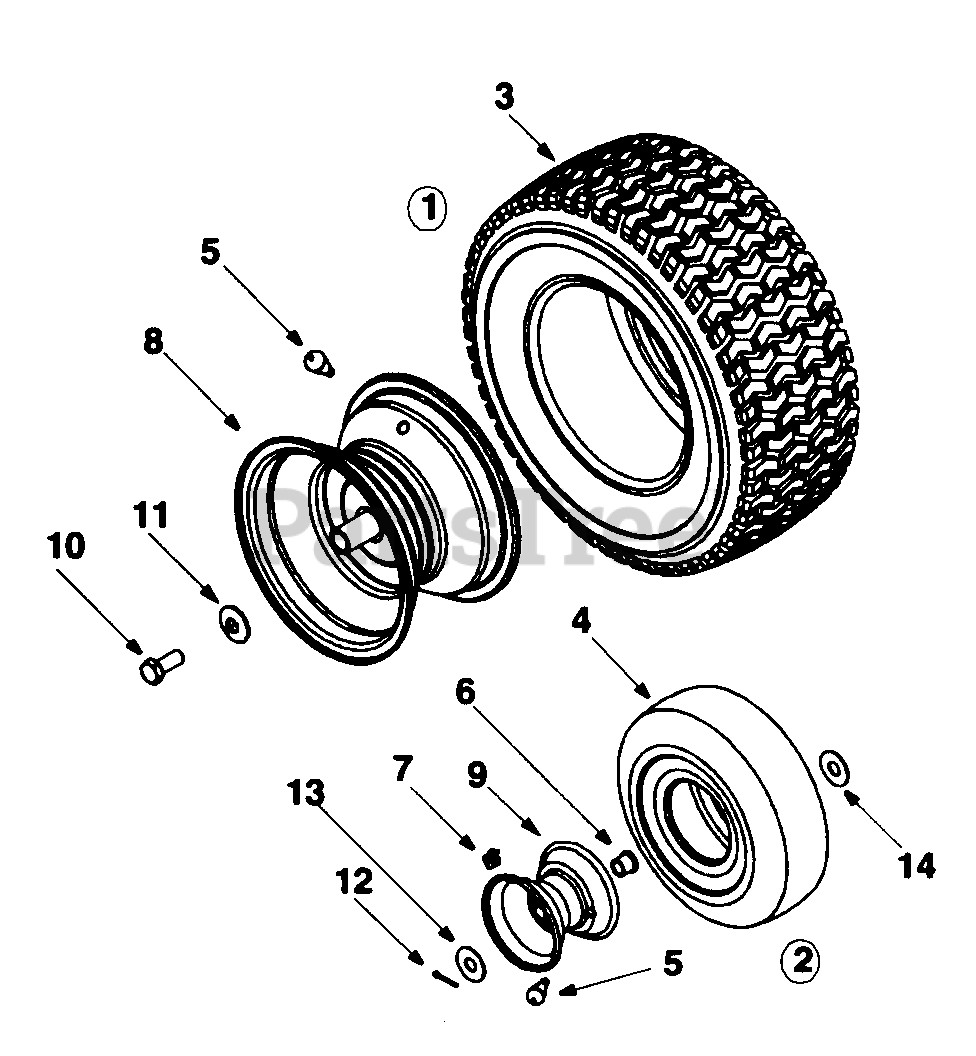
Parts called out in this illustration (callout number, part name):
5	Valve: Tubeless Air
6	Flange Bearing
7	Grease Fitting
8	Rim Assembly: Beige
9	Rim Assembly: Beige
10	Hex Bolt 5/16-24 x .75"
11	Beleville Washer
12	Cotter Pin
13	Flat Washer
14	Flat Washer
